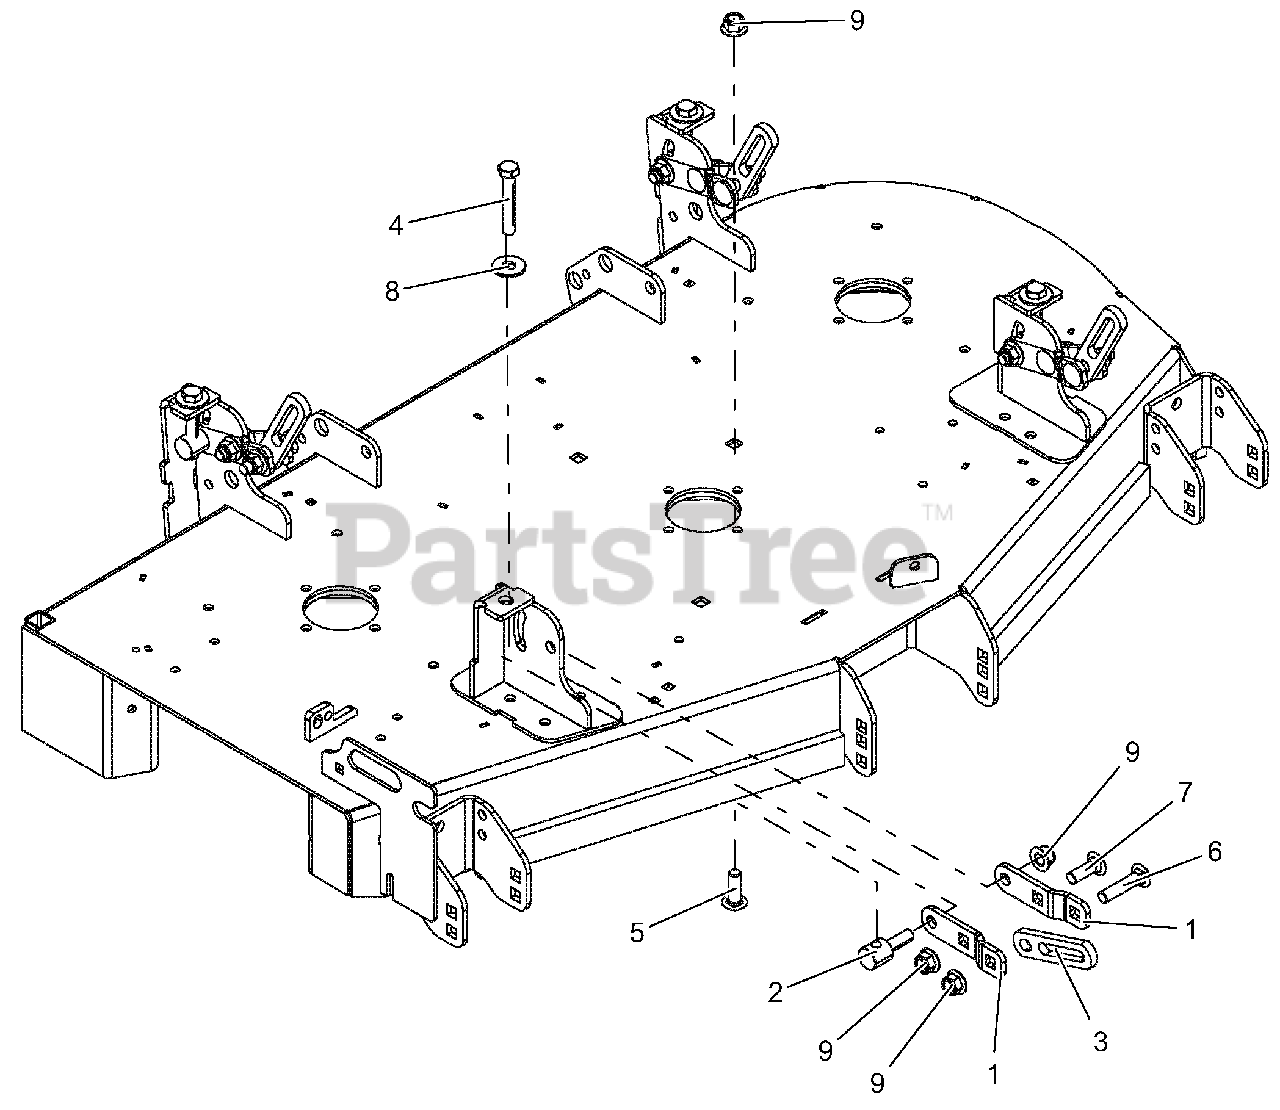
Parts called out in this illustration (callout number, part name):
1	BRKT, DECK LEVELING-BLACK
2	TRUNNION, .50-13
3	LINK, DECK LIFT - SHORT
4	BLT, HEX .500-13 X 3.000 GR5 FTH YZ W/NYLON PATCH
5	BLT-RDHDSQSHNK .50-13X1.50 YWZC
6	BLT-RDHDSQNK .50-13X2.25 G5 Y
7	BLT-RDHDSQNK .50-13X1.50 G5 YWZC
8	WSHR-FL-STL.563X1.38X.109YWZC
9	NUT-LK-NYL-FLG .50-13 YWZC
